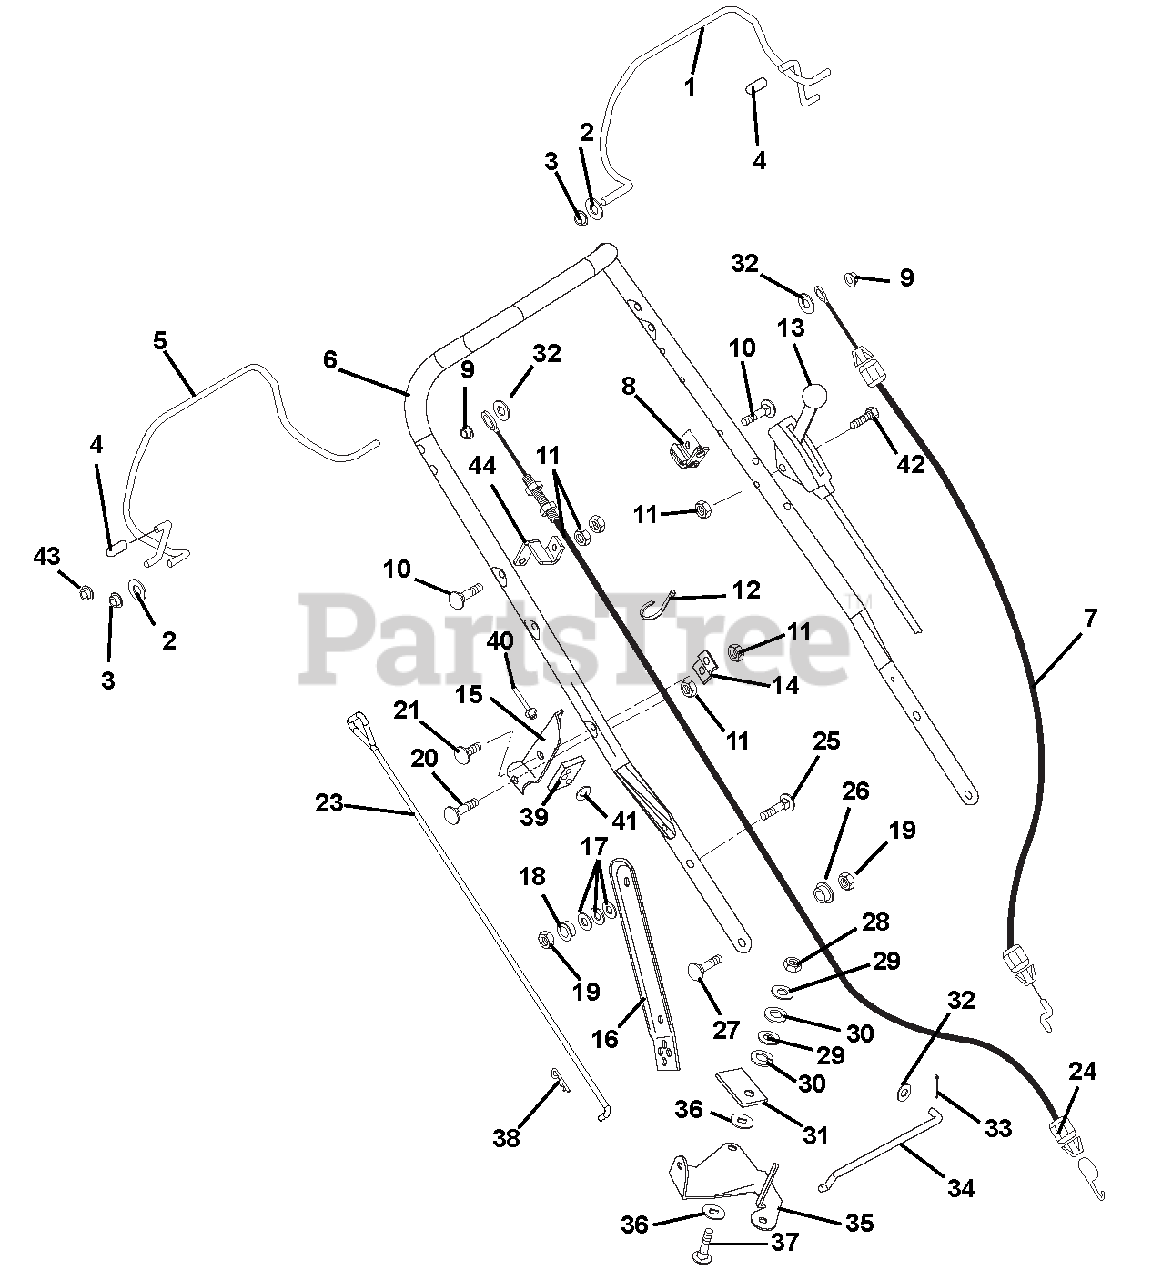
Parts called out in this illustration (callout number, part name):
1	BAIL, ENGINE WELDMENT
2	@WSHR-FL-STL.344X.688X.065YWZC
3	BSHG-FLG .325X.444X.440X.560
4	CAP, VINYL, .25 ID
5	BAIL, TRACTION (WLDMENT)
6	BAR, WBLM HANDLE
7	CABLE, KOHLER/TRAD OPC
7	CABLE, OPC CLASSIC LM CE DOV
8	ANCHOR, WBLM ENGINE CABLE
9	PUSH NUT, .25
10	BLT-RDHDXLSQNK.25-20X1.25 G5ZC
11	@NUT-LK-CTR .25-20 YWZC
12	CABLE TIE LG 5-1/2
13	CABLE, LOCKOUT CONTROL
14	BRACE, SPEED CONTROL
15	BRACKET, SPEED CONTROL
16	LINK, HANDLEBAR ADJUSTMENT LH
16	LINK, HANDLEBAR ADJUSTMENT RH
17	WASHER, BELLEVILLE YWZC
18	BSHG-FLG .325X.500X.513X.875
19	@NUT-LK-CTR .31-18 YWZC
20	@BLT-RDHDSQNK .25-20X1.50 G5YZ
21	@BLT-RDHDSQNK .25-20X.50 G5YZ
22	KNOB, BALL 5/16-18 X 1.5
23	ROD, SPEED CONTROL
24	CABLE, WBLM TRACTION
25	@BLT-RDHDSQNK .31-18X1.00 G5YZ
26	BSHG, FLG .325X.499X.26X.88
27	@BLT-RDHDSQNK .31-18X1.00 G5YZ
28	@NUT-LK-CTR .38-16 YWZC
29	@WSHR-FL-STL.406X.812X.065 YWZ
30	WSHR-LK .375X.115 HVY YWZC
31	PRESSURE FLANGE
32	@WSHR-FL-STL.281X.62X.065 YWZC
33	@PIN-CTR .06X.50 EXTPRSQCT YWZ
34	SHIFT LINK
35	BELL CRANK - SPEED CONTROL
36	FRICTION WASHER
37	@BLT-RHDSSQNK .38-16X1.25 G5YZ
38	PIN-HAIR INT .08X.18X1.18 YWZC
39	SUPPORT PAD
40	RVT .187X.575 DOME AL BLACK
41	@WSHR-FL-STL.219X.50X.049 YWZC
42	BLT-RDHDXLSQNK .25-20X2.0 G5YZ
43	NUT-PUSH .312 DIA. PAL
44	ANCHOR, CABLE
